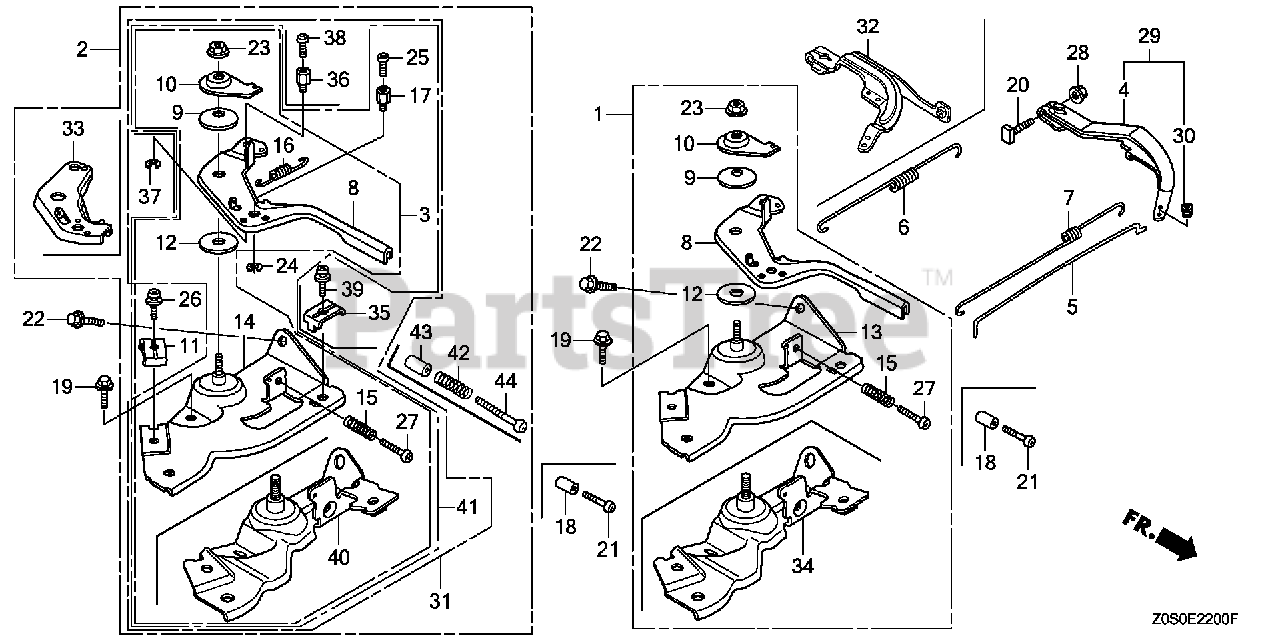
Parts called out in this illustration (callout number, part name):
2	CONTROL ASSY.
4	ARM, GOVERNOR
5	ROD, GOVERNOR
6	SPRING, GOVERNOR
7	SPRING, THROTTLE RETURN
9	SPRING, LEVER
10	WASHER, CONTROL LEVER
11	HOLDER, CABLE
12	SPACER, CONTROL LEVER
16	SPRING, CABLE RETURN
17	HOLDER, WIRE
19	BOLT, FLANGE (6X12) (CT200)
20	BOLT, GOVERNOR ARM
22	BOLT, FLANGE (6X20) (CT200)
23	NUT, SELF-LOCK (6MM)
24	CIRCLIP (5MM) Use from Engine SN 2327377.
25	SCREW, PAN (4X6)
26	SCREW, PAN (5X16)
28	NUT, FLANGE (6MM)
33	LEVER, CONTROL
40	BASE, CONTROL
42	SPRING, CONTROL ADJUSTING Use from Engine SN 2327377.
43	COLLAR, STOPPER
44	SCREW, RECESSED (5X25)
